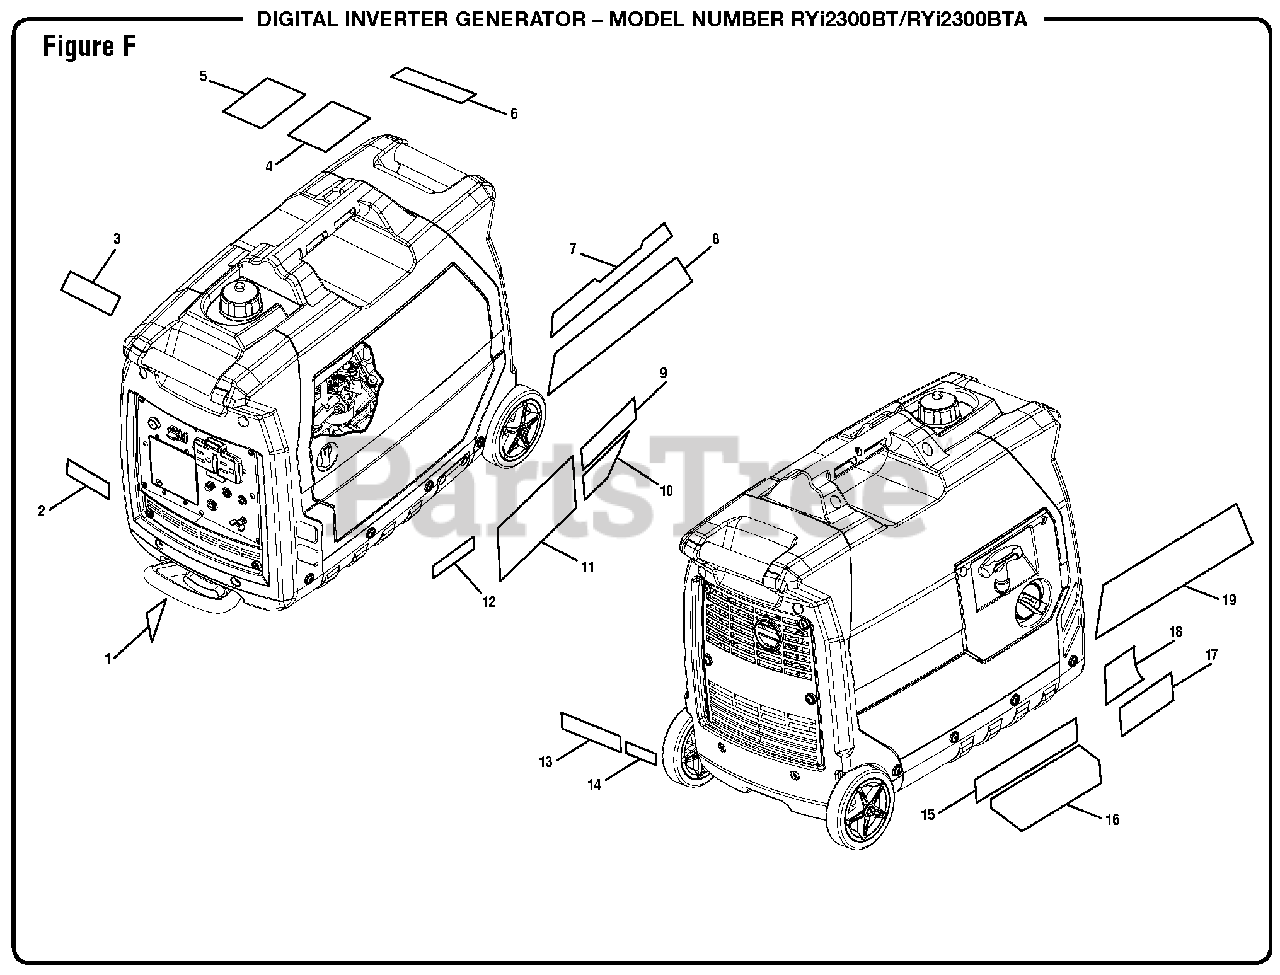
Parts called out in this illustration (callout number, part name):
1	Handle Release Label
2	Logo Label
3	Fuel Stabilizer Label
4	CPSC Label
5	Danger Label
6	Ground Warning Label (En/Fr)
7	Fire Distance Label
8	Performance Label (Maintenance Door)
9	Inquiries Label
10	Lubricant Label
11	Maintenance Door Label
12	Maintenance Label
13	Combustion Label
14	Hot Surface Label
15	Start Label
16	Gen Control/Bluetooth Label
17	Easy Start Logo Label
18	Choke Label
19	Performance Label
